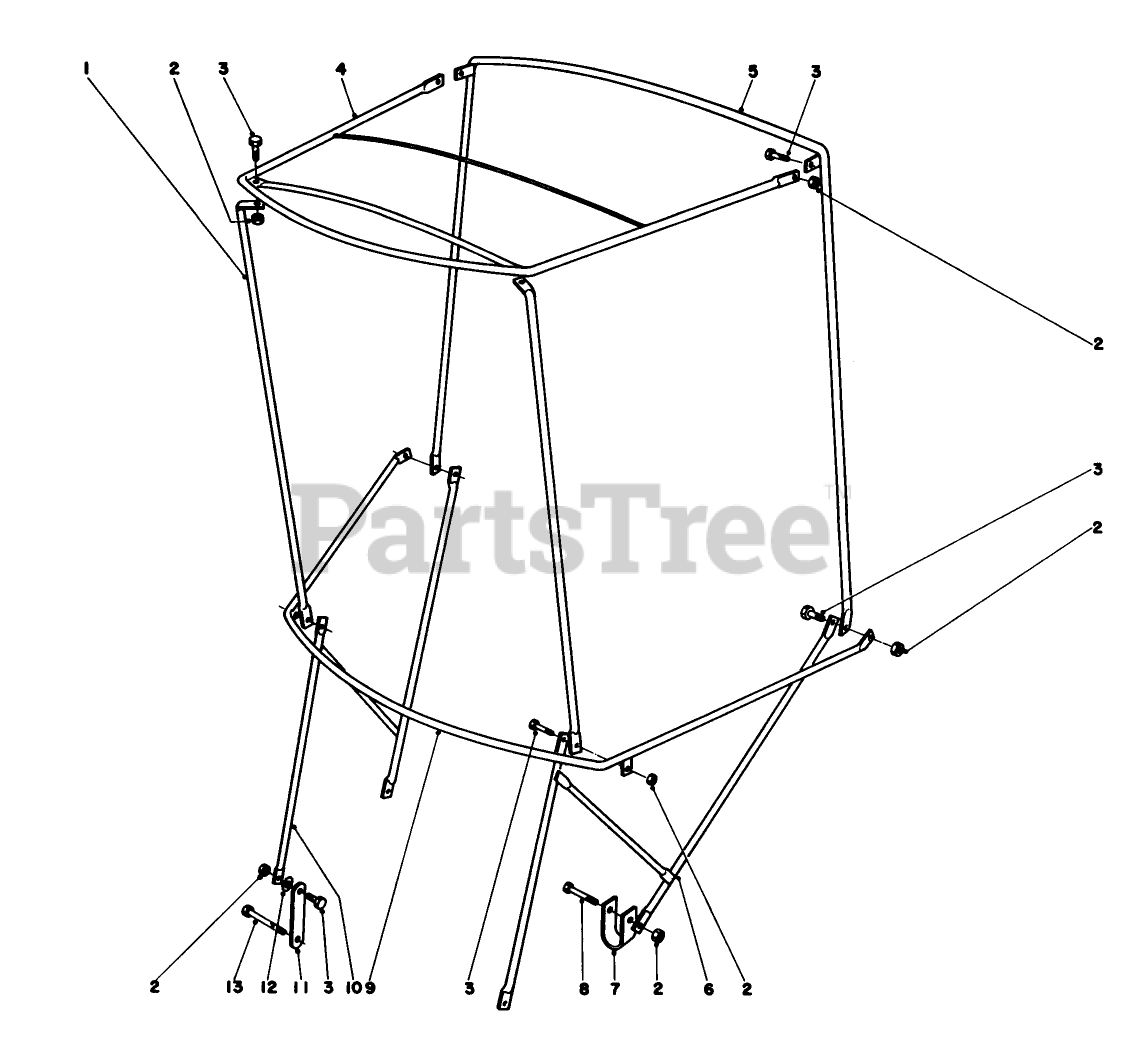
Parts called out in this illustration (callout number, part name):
3	SCREW-HH
8	SCREW-HH
12	WASHER-LOCK/EXT
13	SCREW-HH
